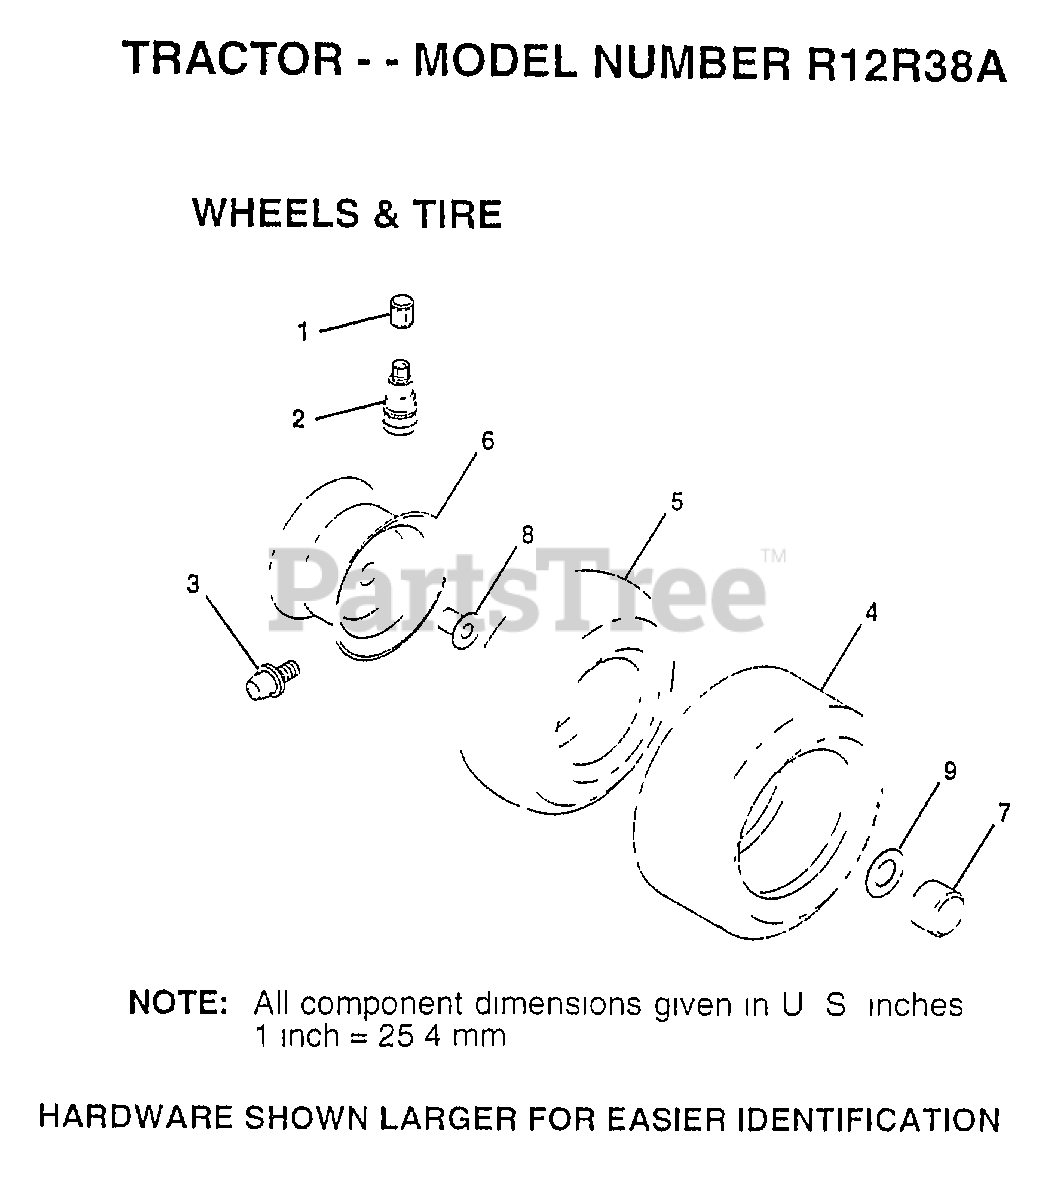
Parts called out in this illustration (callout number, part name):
1	VALVE CAP
2	VALVE STEM LT
3	FITTING LT
5	TUBE.16X6.5/7.5-8
5	TUBE.5.3/4.5/6
6	"RIM FRONT 6"""
6	"RIM ASM REAR 8"""
7	HUB CAP
8	"FLANGE, BEARING"
9	WASHER
